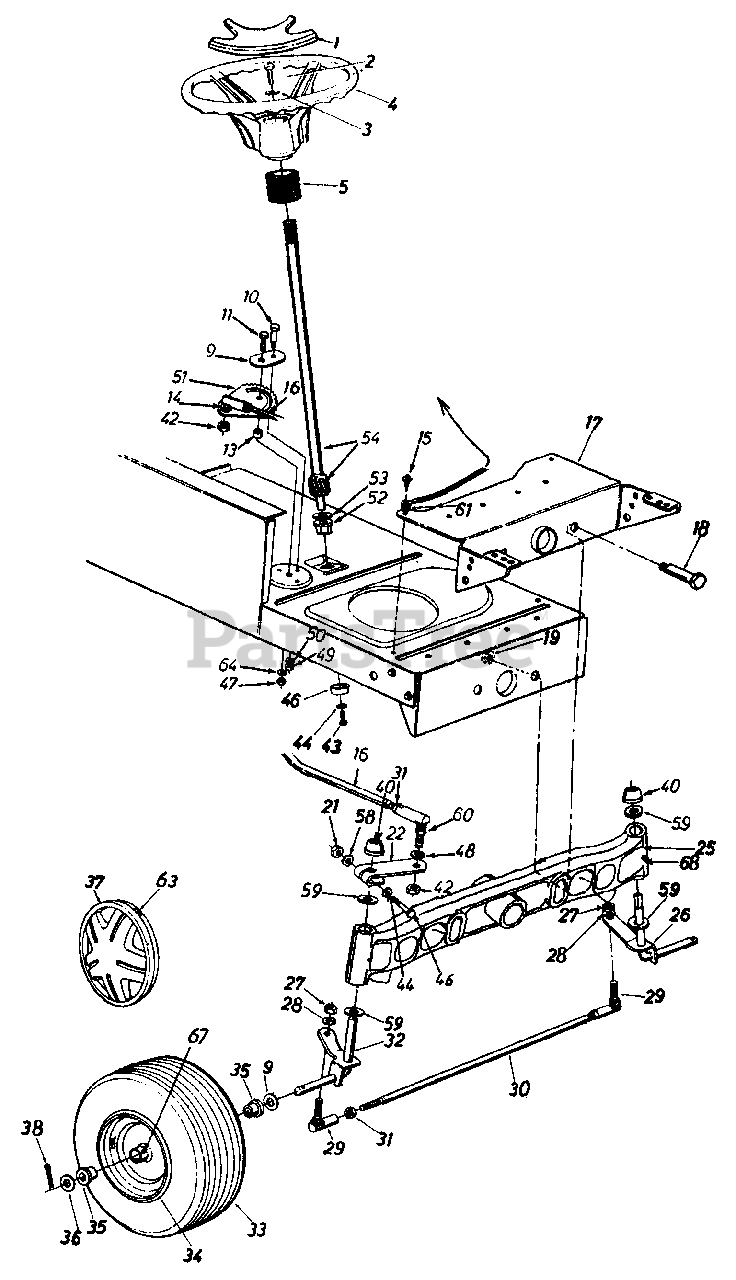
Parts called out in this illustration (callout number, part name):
1	Steering Wheel Cap
2	Hex Bolt 5/16-18 x 1" Lg.
3	Belleville Wash. .345" I.D.
4	Steering Wheel
5	Steering Bellow - 9"
9	Retainer Plate
10	Shoulder Bolt .437" Dia. x .35" Lg.- 5/16-18 Thd.
11	Hex Bolt 3/8-24 x 1.0" Lg. (Grade 5)
13	Spacer.380" I.D. x .625" O.D. x .227
14	L-Wash. 3/8" I.D. (H.D.)
15	Hex Wash. Hd. Self-Tap Scr.
16	Steering Drag Link
18	Shoulder Bolt .498" Dia. x 2.04" Lg.- 3/8-16 Thd.
19	Flanged Hex Nut 3/8-16 Thd.
21	Hex L-Nut 5/16-24 Thd.
22	Steering Arm Front Axle
25	Pivot Bar Ass'y.
26	Front Axle Ass'y.- L.H.
27	Hex Nut 3/8-24 Thd.
28	L-Wash. 3/8" I.D.
29	Ball Joint 3/8-24 Thd.
31	Hex Jam Nut 3/8-24 Thd.
32	Front Axle Ass'y.- R.H.
36	Fl-Wash. .635" I.D. x 1.59" O.D.
37	Hub Cap
38	Cotter Pin 1/8" Dia. x 1.25"
40	Push Cap 5/8" Dia. Rod
42	Hex Jam Nut 3/8-24 Thd.
43	Torx Bolt 5/16-18 x .63" Lg.
44	L-Wash. 5/16" I.D.
46	Cap
47	Hex Cent. L-Nut 3/8-24 Thd.
49	Hex Cent. L-Nut 5/16-18 Thd.
50	L-Wash. 5/16" I.D.
51	Steering Gear Segment
52	Hex, Flg. Brg. 5/8" I.D.
53	Fl-Wash. (Hardened)
54	Steering Shaft
58	Wave-Wash. .32" I.D. x .62" O.D
59	Fl-Wash. (Hardened)
60	Drag Link Ball Joint 3/8-24 Thd.
61	Ext. L-Wash. 5/16" I.D.
63	Spring Clip
64	Bell-Wash. .39" I.D. x 1.38" O.D.
67	Grease Fitting
68	Grease Fitting
